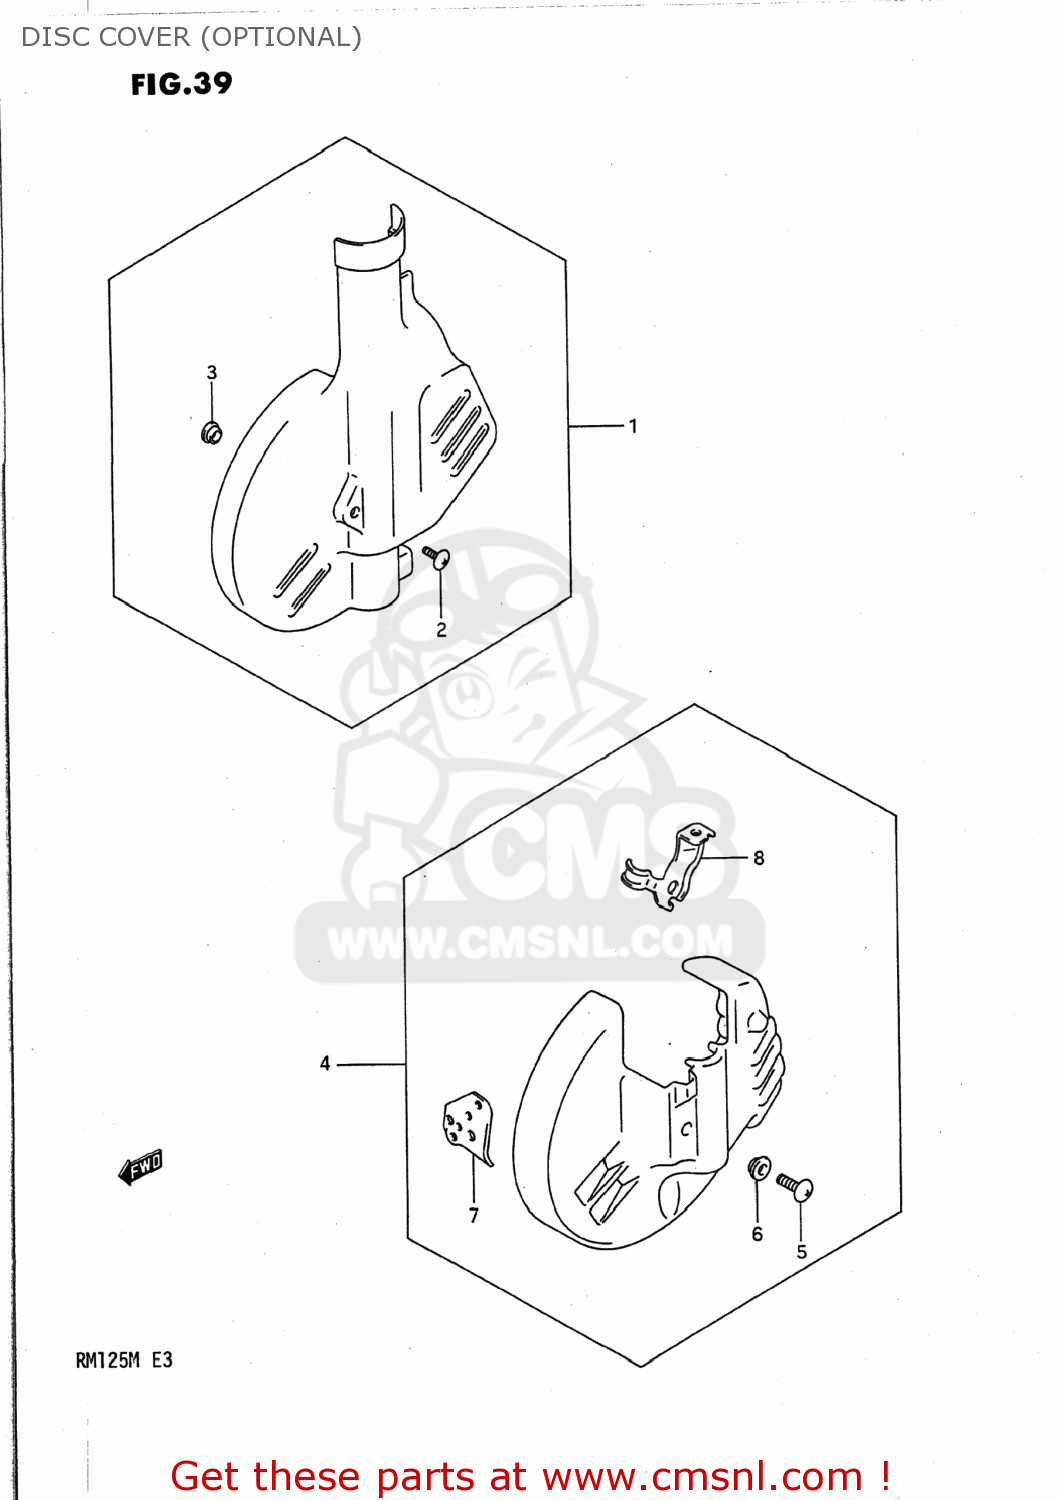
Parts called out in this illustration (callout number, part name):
1	COVER SET,FRONT DISC
2	SCREW(8X12)
3	WASHER
4	COVER SET,FRONT DISC
5	SCREW 6X12
6	WASHER
7	CLAMP,FRONT BRAKE HOSE
8	CLAMP,FRONT BRAKE HOSE
